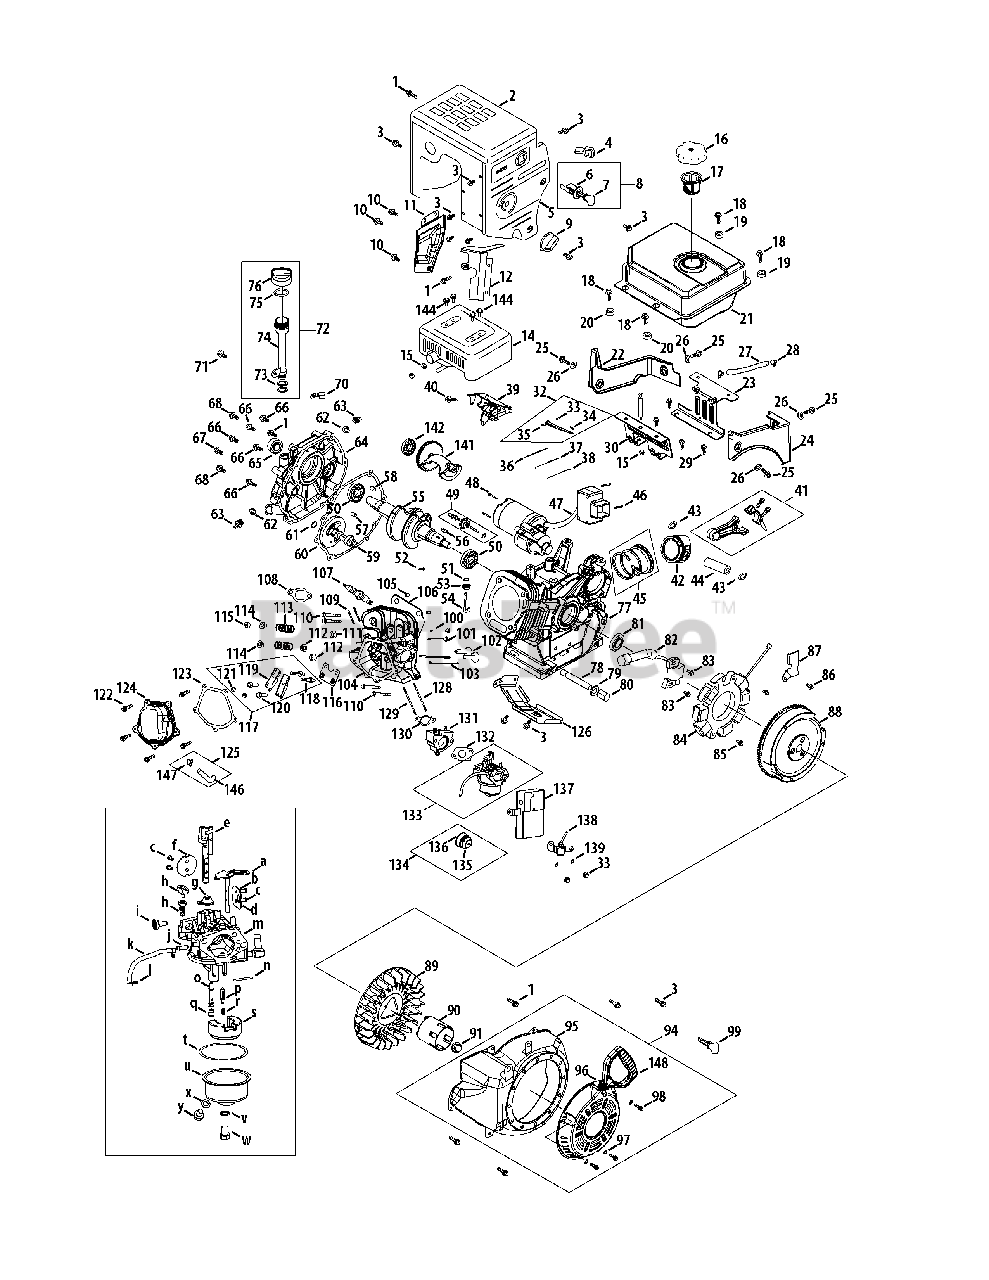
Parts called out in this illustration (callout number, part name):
1	Bolt, M6 x 16
2	Muffler Shield
3	Bolt, M6 x 12
4	Throttle Control Knob
5	Control Panel
7	Key
8	Key Switch Ass’y
9	Choke Knob
10	Bolt, Flange, M6 x 10
11	Muffler Baffle
12	Carb Isolator Bracket
14	Muffler Ass’y
15	Nut, M8 - 1.25
16	Fuel Cap Ass’y
17	Fuel Level Indicator
18	Flange Bolt, M8 x 20
19	Bushing, Gas Tank
20	Bushing, Gas Tank
21	Fuel Tank Ass’y
22	Fuel Tank Shroud
23	Rear Mounting Bracket Ass’y
24	Engine Shroud
25	Bolt, M6 x 16
26	Bush - Washer
27	Fuel Line Kit
28	Fuel Line Clamp
29	Bolt, M8 x 14
30	Fuel Tank Mounting Bracket
33	Nut, M6
34	Governor Arm Bolt
35	Governor Arm
36	Governor Spring
37	Throttle Linkage Spring
38	Throttle Linkage
39	Primer Bracket
40	Bolt, Flange, M6 x 14
41	Connecting Rod Ass’y
42	Piston
43	Piston Pin Snap Ring
44	Piston Pin
45	Piston Ring Set
46	Bolt, M4 x 55
47	Startup Electromotor
48	Bolt, M8 x 55
49	Governor Gear/Shaft Ass’y
50	Radial Ball Bearing
51	Washer
52	Cotter Pin
53	Governor Seal
54	Governor Arm Shaft
55	Crankshaft Kit
56	Woodruff Key
57	Dowel Pin, 9 x 12
58	Dowel Pin, 7 x 14
59	Camshaft Ass’y
60	Crankcase Cover Gasket
61	Washer
63	Oil Filler Plug Ass’y
64	Crankcase Cover Kit
65	Oil Seal
66	Bolt, M8 x 38
67	Bolt, M8 x 45
68	Bolt, M8 x 35
70	Dipstick Clamp
71	Bolt, M6 x 8
73	Fill Tube O-Ring
73	Oil Fill Tube O-Ring
74	Oil Fill Tube Assembly
75	Dipstick O-Ring
76	Dipstick Ass'y
77	Crankcase Kit
78	Oil Drain Pipe Ass’y
79	Oil Drain Washer
80	Drain Plug
81	Oil Seal
82	Ignition Coil Ass’y
83	Ignition Coil Bolt
84	Coil Assy. Charge
85	Bolt, M6 x 30
86	Bolt, M6 x 8
87	Alternator Wire Clamp Bracket
88	Flywheel
89	Fan, Cooling
90	Starter Cup
91	Nut, Special, M16 x 1.5
95	Blower Housing
96	Recoil Starter
97	Gasket
98	Bolt, M6 x 10
99	Key
100	Valve Kit
101	Valve Kit
102	Tappet
103	Push Rod (2X)
104	Cylinder Head Ass'y
105	Dowel Pin, 12 × 20
106	Gasket, Cylinder Head
107	Spark Plug/F6rtc
108	Exhaust Pipe Gasket
109	Stud, M8 x 48.5
109	Muffler Stud Ass’y
110	Bolt, M10 × 1.25 × 87
111	Intake Valve Seal
112	Valve Spring Retainer
113	Valve Spring
114	Retainer, Ex.Valve Spring
115	Adjuster, Exh Valve
116	Push Rod Guide
117	Rocker Arm Ass’y
118	Bolt, Pivot
119	Rocker Arm
120	Adjusting Nut, Valve
121	Nut, Pivot Locking
122	Valve Cover Bolt
123	Valve Cover Gasket
124	Valve Cover
126	Cylinder Baffle
128	Stud, M6 x 8 x 98
129	Stud, M6 x 8 x 118
130	Carburetor Insulator Gasket
131	Carburetor Insulator Plate
132	Carburetor Gasket
133	Carburetor Ass’y
134	Primer Ass’y
135	Primer Bulb
137	Heater Box
138	Choke Control
139	Lock Washer
141	Camshaft Gear Ass’y
142	Bearing
146	Breather Hose
148	Starter Handle
149	Valve Cover Kit
150	Oil Drain Ass’y
